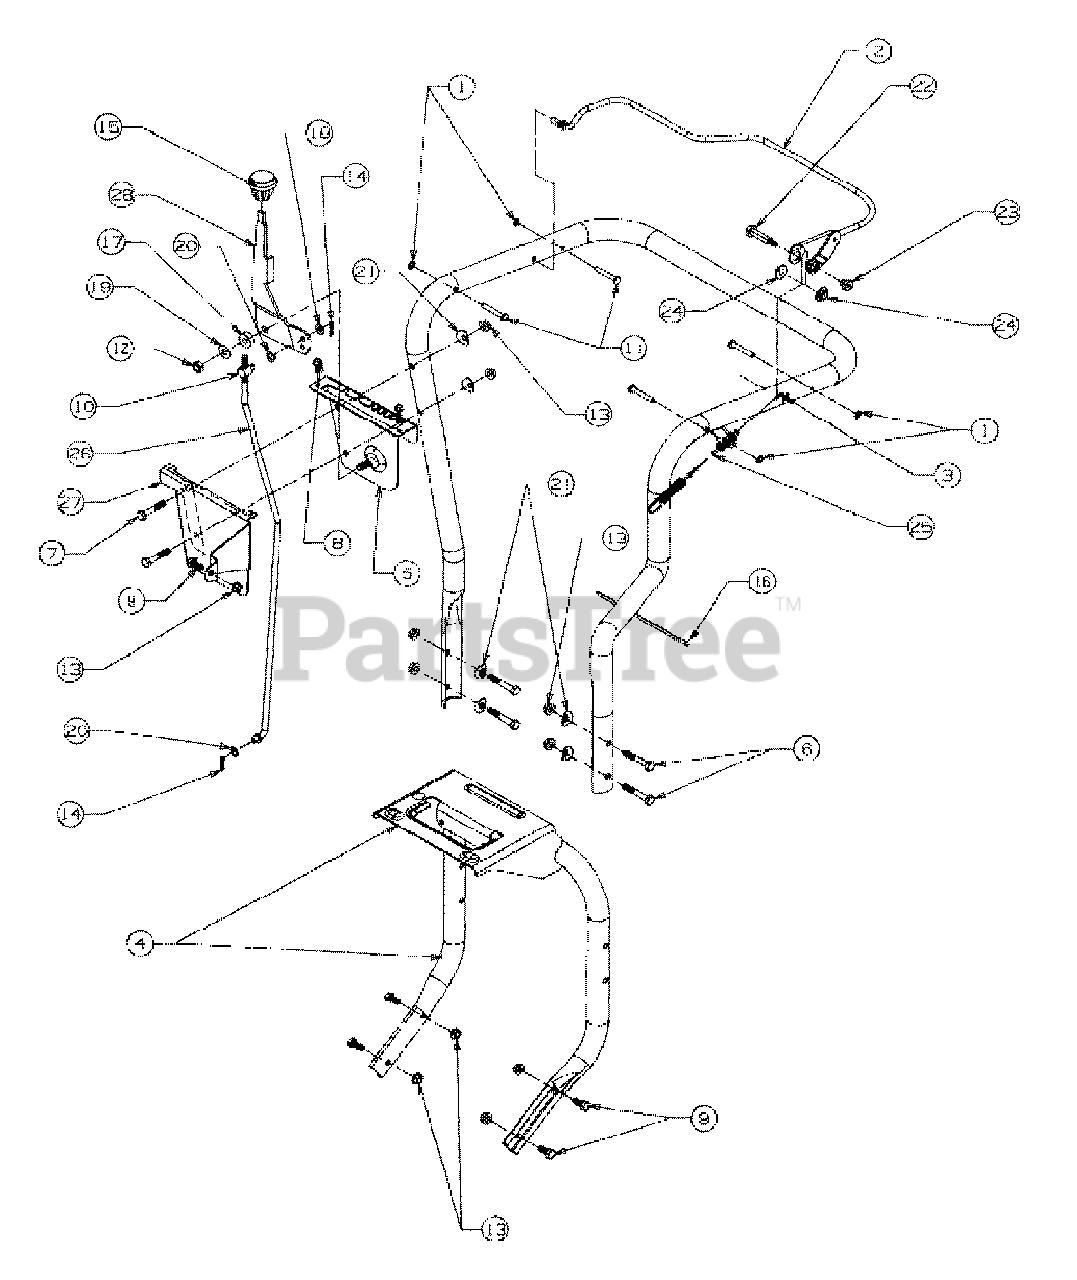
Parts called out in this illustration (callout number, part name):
1	PUSH NUT
7	SCREW-HEX
8	SCREW-HEX
9	SCREW-HEX
10	FERRULE
11	PIN-STUD
12	NUT-HEX LOCK
13	NUT-HEX LOCK
14	PIN-COTTER
15	KNOB-SHIFT
16	CABLE TIE
17	WASHER-RUBBER
18	WASHER-FLAT
19	WASHER-FLAT
20	WASHER-SPRING
21	WASHER-SADDLE
22	SCREW-SHOULDER
23	NUT-SHOULDER
24	BEARING-FLANGE PLASTIC
25	CABLE-CLUTCH
26	ROD-SHIFT
